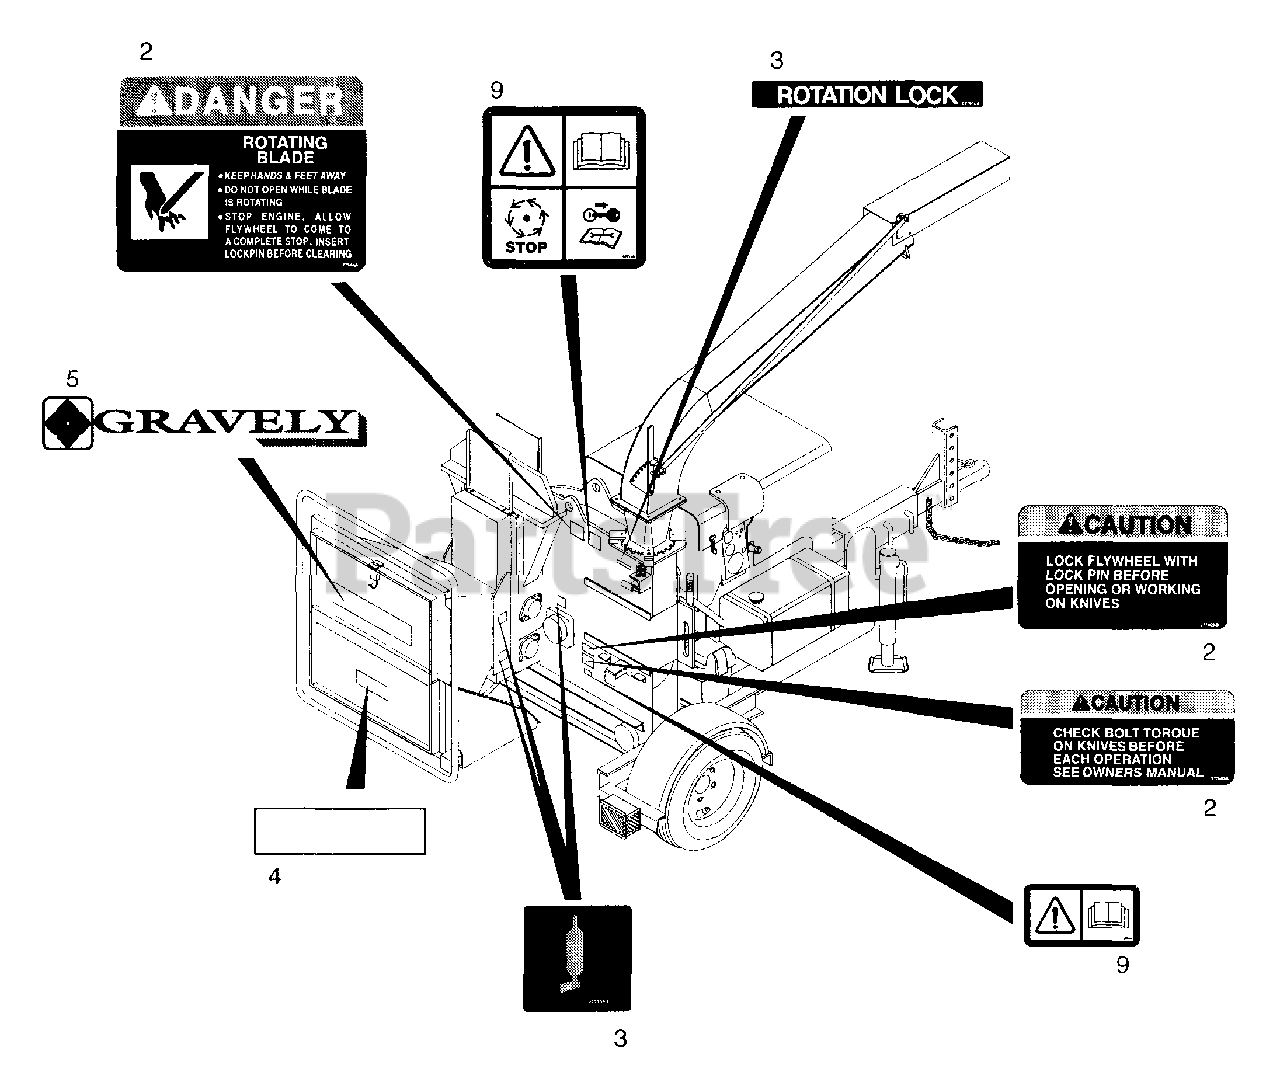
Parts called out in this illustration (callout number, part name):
2	Decal-Set Large Chippers
3	Decal-Set Chipper Black/White
4	Decal-Model Designation 944
5	Decal-Warning-Protective
9	Decal-Set Chipper CE
